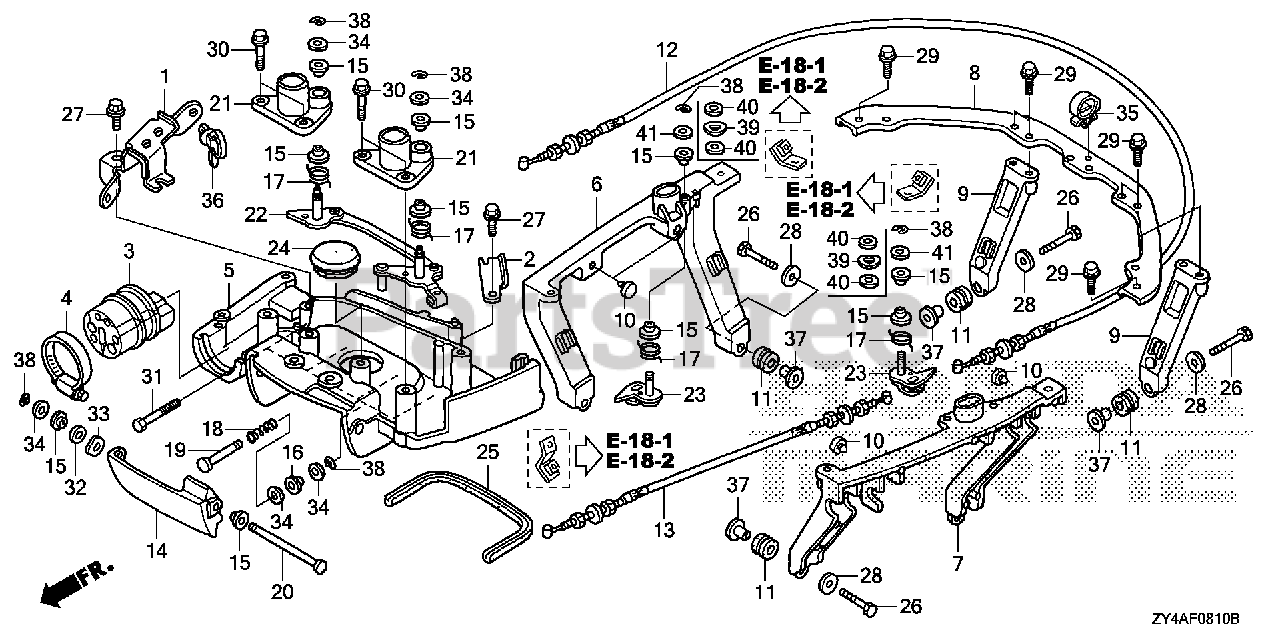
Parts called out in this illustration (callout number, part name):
2	PLATE, STARTER CABLE
3	GROMMET A, CASE (LOWER)
4	BAND, CASE GROMMET (LOWER)
5	BRACKET, FR. COVER *NH8* (DARK GRAY)
6	BRACKET, R. SIDE COVER
7	BRACKET, L. SIDE COVER
8	BRACKET A, RR. COVER
9	BRACKET B, RR. COVER
10	RUBBER, STOPPER
11	RUBBER, FR. CARRIER CUSHION
12	CABLE A, COVER LOCK
13	CABLE B, COVER LOCK
14	LEVER, COVER LOCK *NHB14M* (AQUA MARINE SILVER METALLIC)
14	LEVER, COVER LOCK *NH565* (GRAND PRIX WHITE)
15	BUSH A, COVER LOCK
16	BUSH B, COVER LOCK
17	SPRING, COVER LOCK HOOK
18	SPRING, LOCK LEVER RETURN
19	SHAFT, COVER OPEN
20	SHAFT, FR. LOCK
21	HOLDER, STRIKER
22	LOCK ASSY., FR.
23	LOCK, SIDE
24	CAP, L. SIDE COVER
25	SEAL D, COVER (LOWER)
26	BOLT, HEX. (8X35)
27	BOLT, FLANGE (6X14)
28	WASHER, PLAIN (8MM)
29	BOLT, FLANGE (6X12)
30	BOLT, FLANGE (6X20)
31	BOLT, FLANGE (8X22)
32	WASHER, PLAIN (10MM)
33	WASHER, WAVE (10MM)
34	WASHER, PLAIN (8MM)
35	CLIP, HARNESS
36	CLIP, HARNESS BAND (145MM) (BLACK)
37	COLLAR (8.5X14.5)
38	E-RING (6MM)
39	WASHER, WAVE (8MM)
40	WASHER, PLAIN (8MM)
